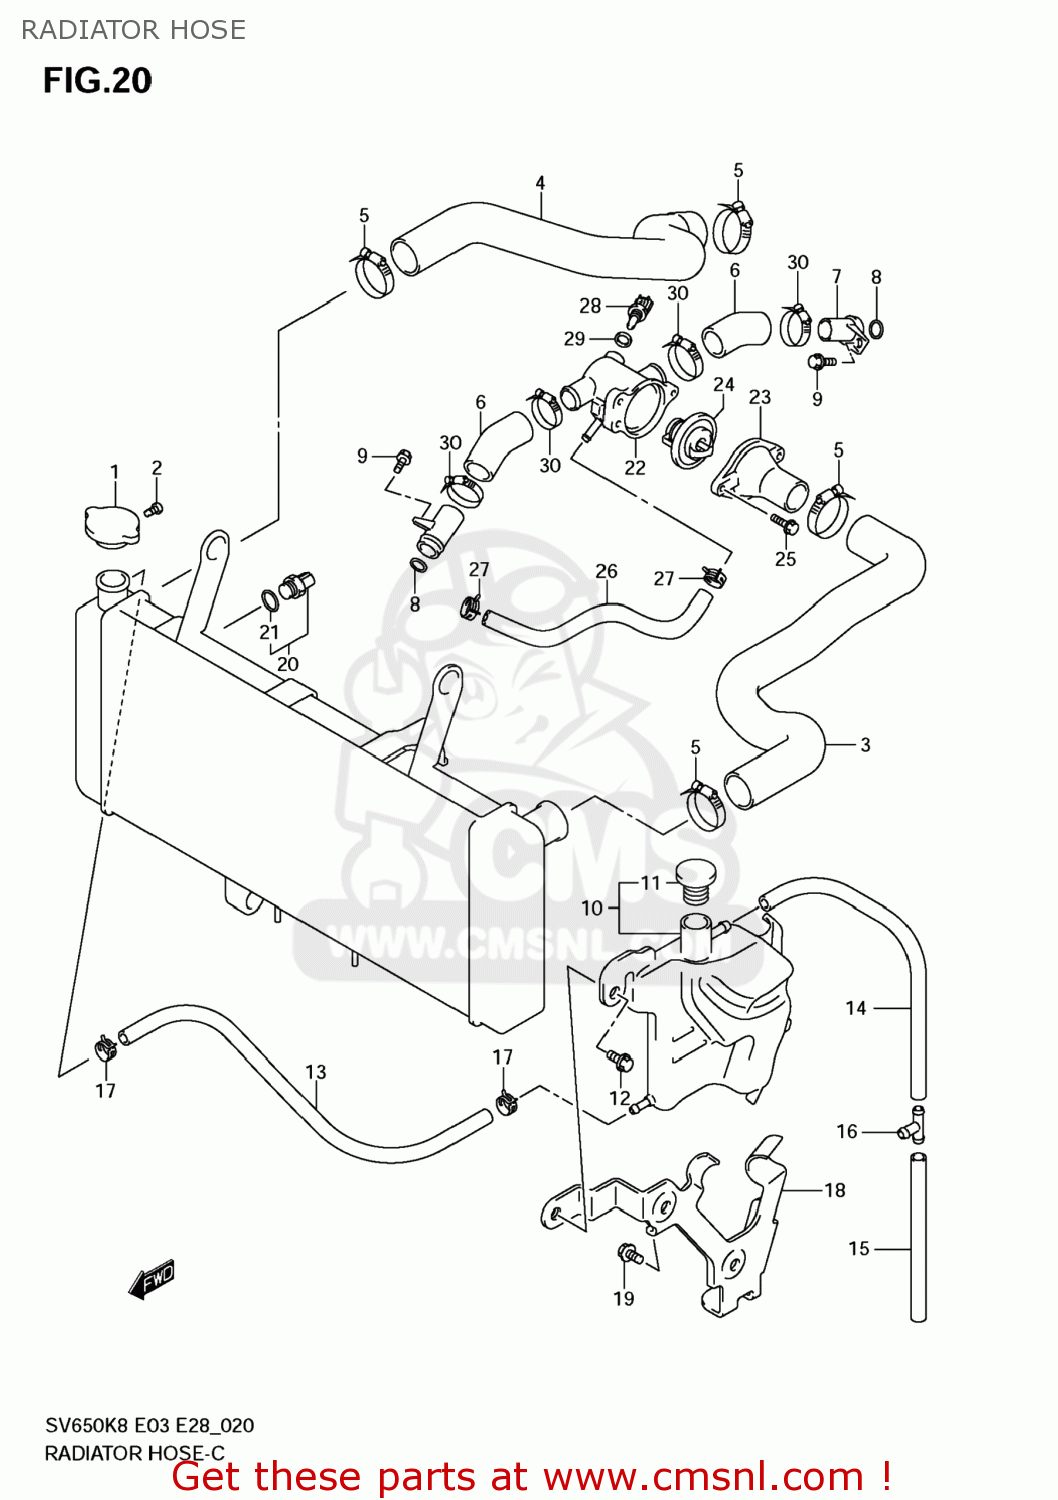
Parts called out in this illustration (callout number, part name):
1	CAP,RADIATOR(1.1)
2	SCREW,RADIATOR CAP
3	HOSE,RADIATOR INLET
4	HOSE,RADIATOR OUTLET
5	CLAMP
6	HOSE,CONNECTOR INLET
7	UNION,CONNECTOR HOSE
8	O RING(D:3.2,ID:17.8)
9	BOLT
10	TANK ASSY,RESERVOIR
11	CAP,RESERVOIR TANK
12	BOLT(6X12)
13	HOSE(5X9X600)
14	HOSE(5X9X600)
15	HOSE(7X10.2X600)
16	3 WAY
17	CLIP
18	BRACKET,RESERVOIR TANK
19	BOLT
20	SWITCH,FAN THERMO
21	O-RING
22	CONNECTOR,THERMOSTAT INLET
23	CAP,THERMOSTAT CONNECTOR
24	THERMOSTAT,WATER
25	BOLT
26	HOSE,CONNECTOR TO WATER PUMP
27	CLAMP
28	SENSOR,WATER TEMP
29	GASKET(12X17X1) (NAS)
30	CLAMP
